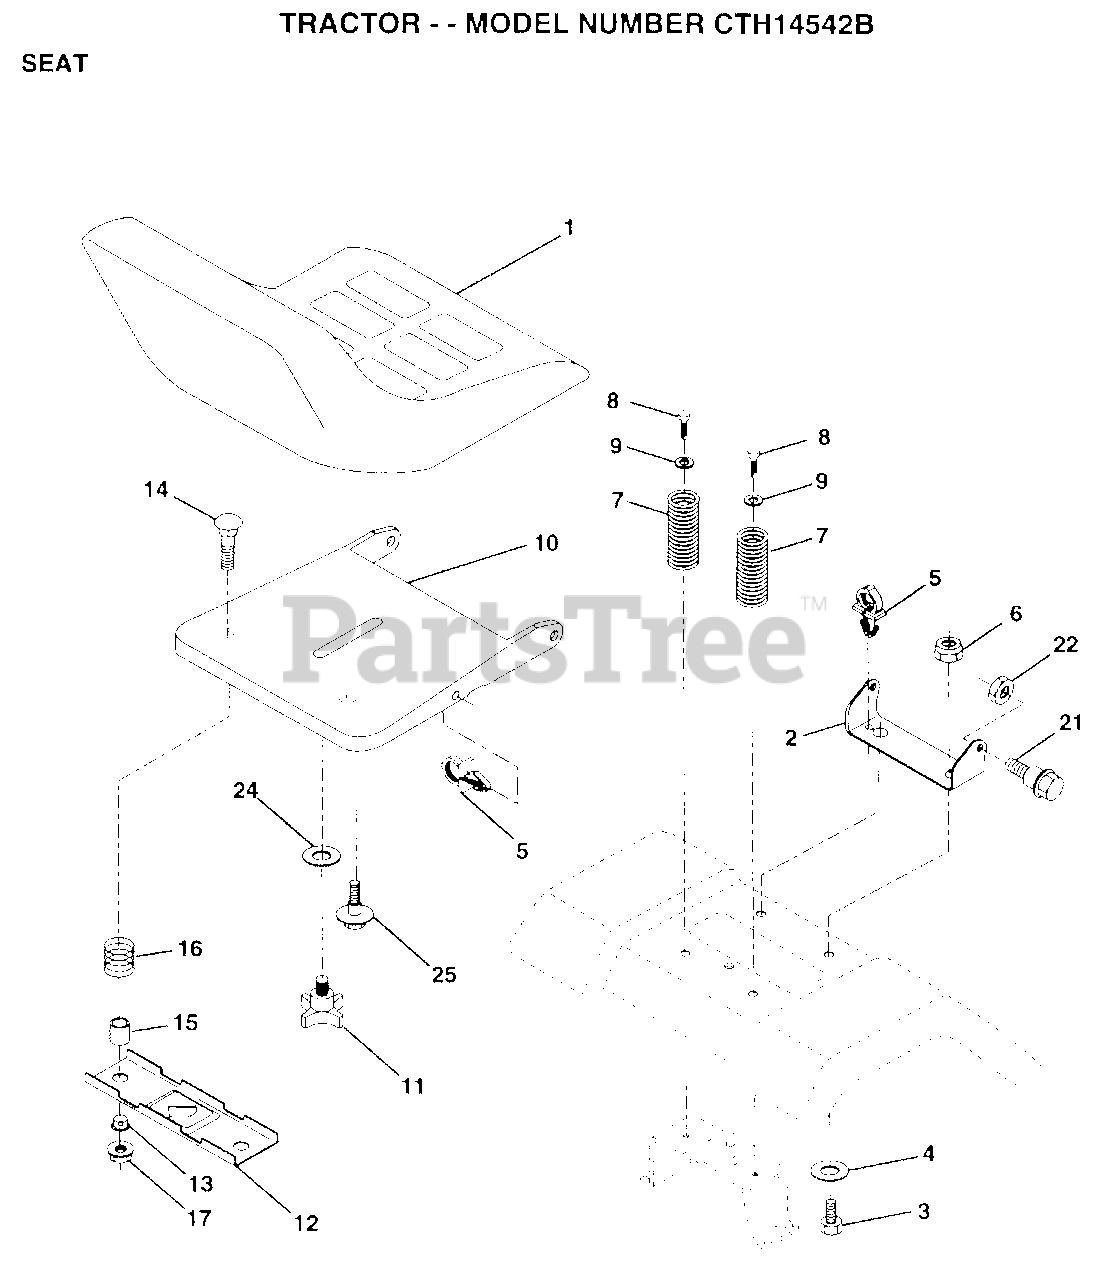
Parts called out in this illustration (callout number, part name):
2	BRACKET PVT SEAT
3	BOLT
4	WASHER PM
5	CLIP.PUSH-IN.HING
6	NUT
7	SPRING COMPRESSIO
8	SCREW GTV
9	WASHER
11	"KNOB 1/2"" YT"
12	BRKT SWITCH
13	BUSHING
15	SPACER SPLIT
16	SPRING COMPRESSED
21	BOLT.SHLD.5/16-18
24	WASHER
25	"BOLT,SHOULDER"
